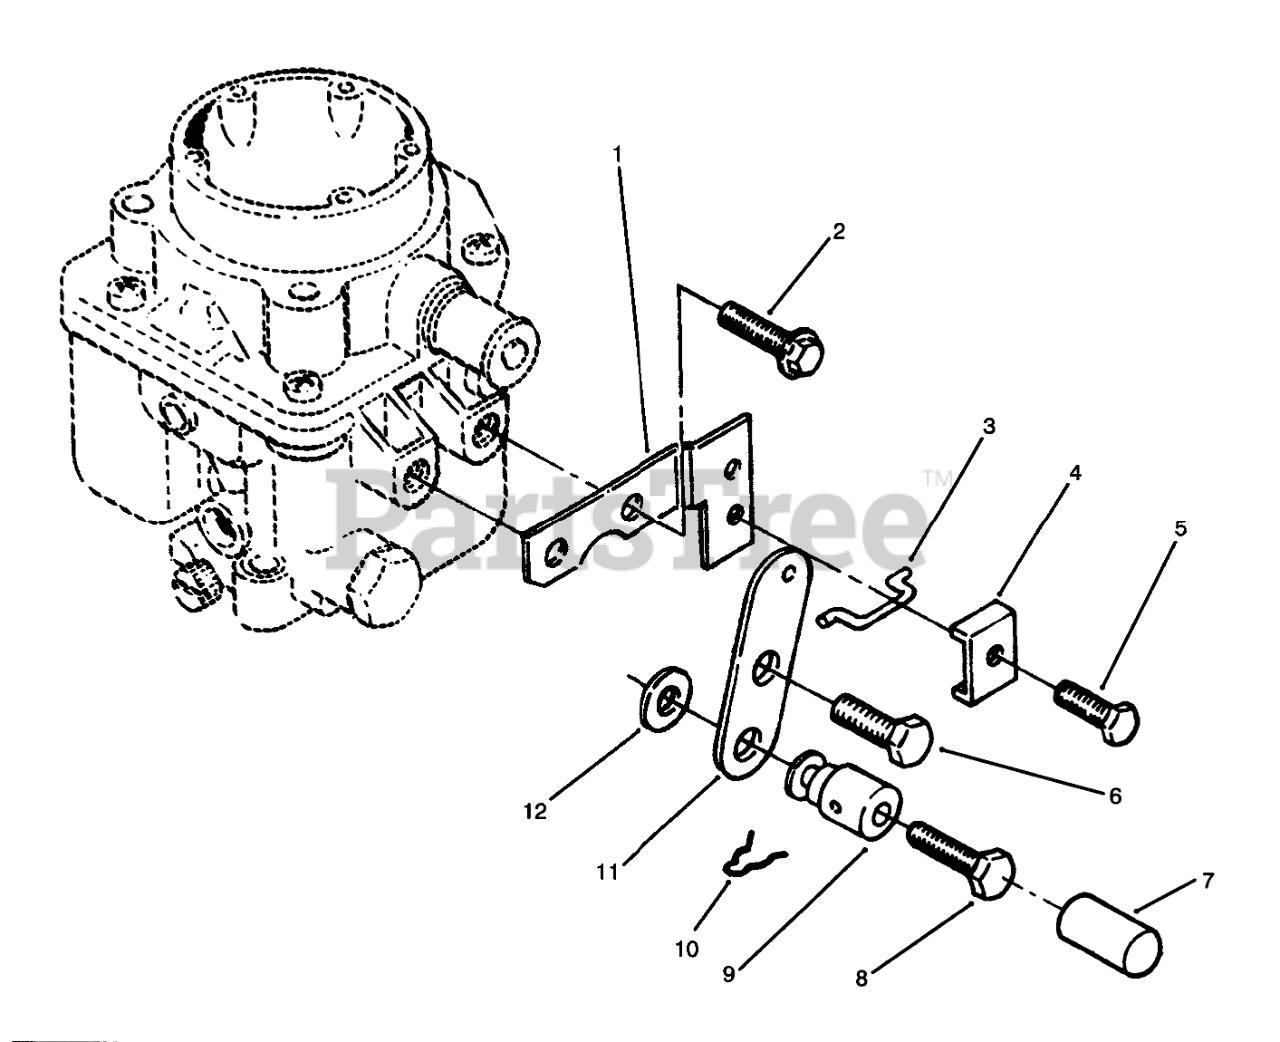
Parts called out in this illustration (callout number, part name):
1	BRACKET
2	SCREW-HWH
3	LINK-CHOKE
5	SCREW-TAPPING
6	MACHINE SCREW
8	SCREW
9	SWIVEL-CHOKE LEVER
10	PIN-COTTER
11	CHOKE-LEVER (PRIMED)
12	Washer
